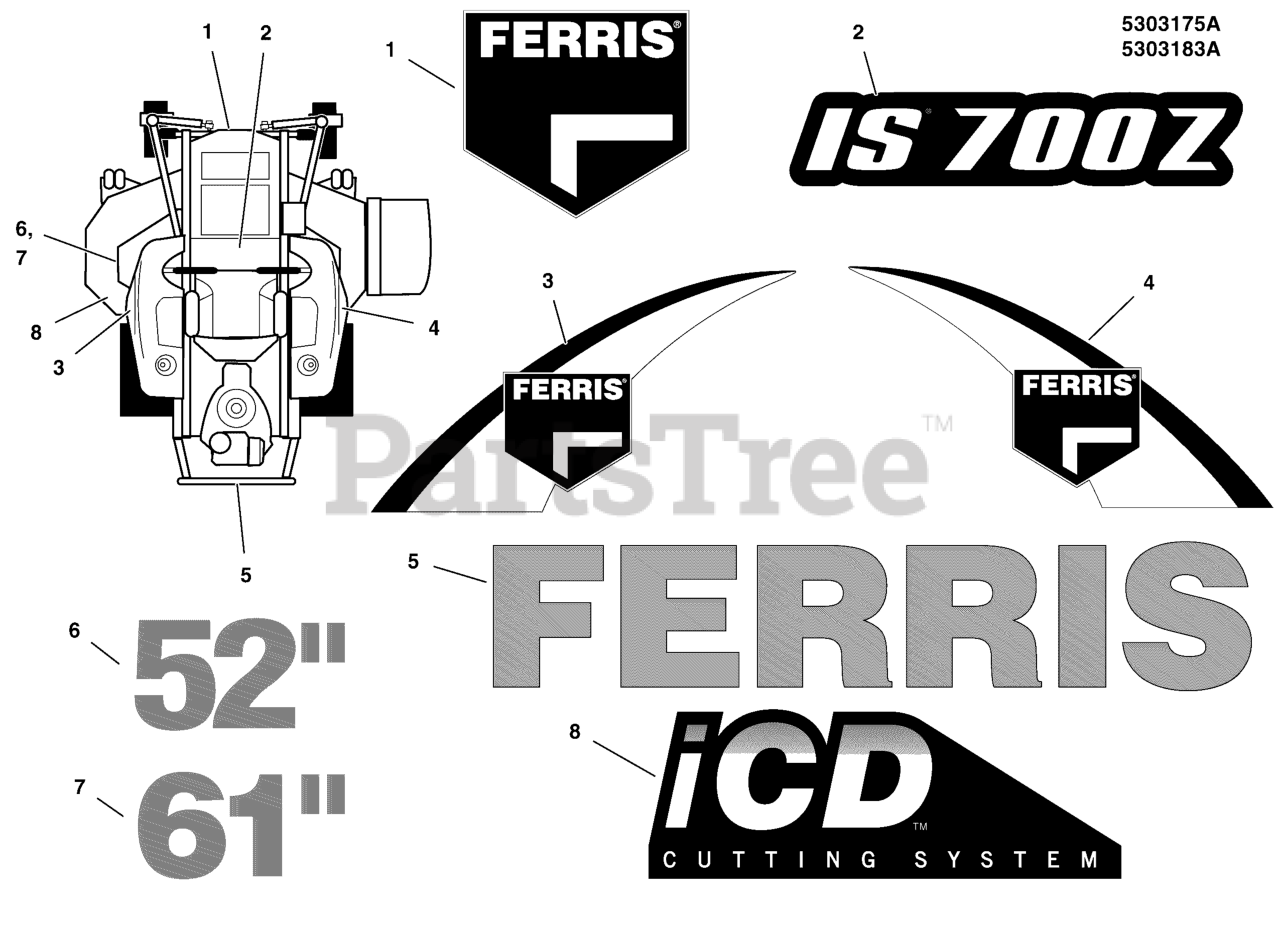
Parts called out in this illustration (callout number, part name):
1	DECAL, BRAND
2	DECAL, MODEL
3	DECAL, Model, Left Hand
4	DECAL, MODEL, RIGHT HAND
5	DECAL, FERRIS, 2.23" X 11.39"
6	DECAL, 52
7	DECAL, 61
8	DECAL, iCD CUTTING SYSTEM
